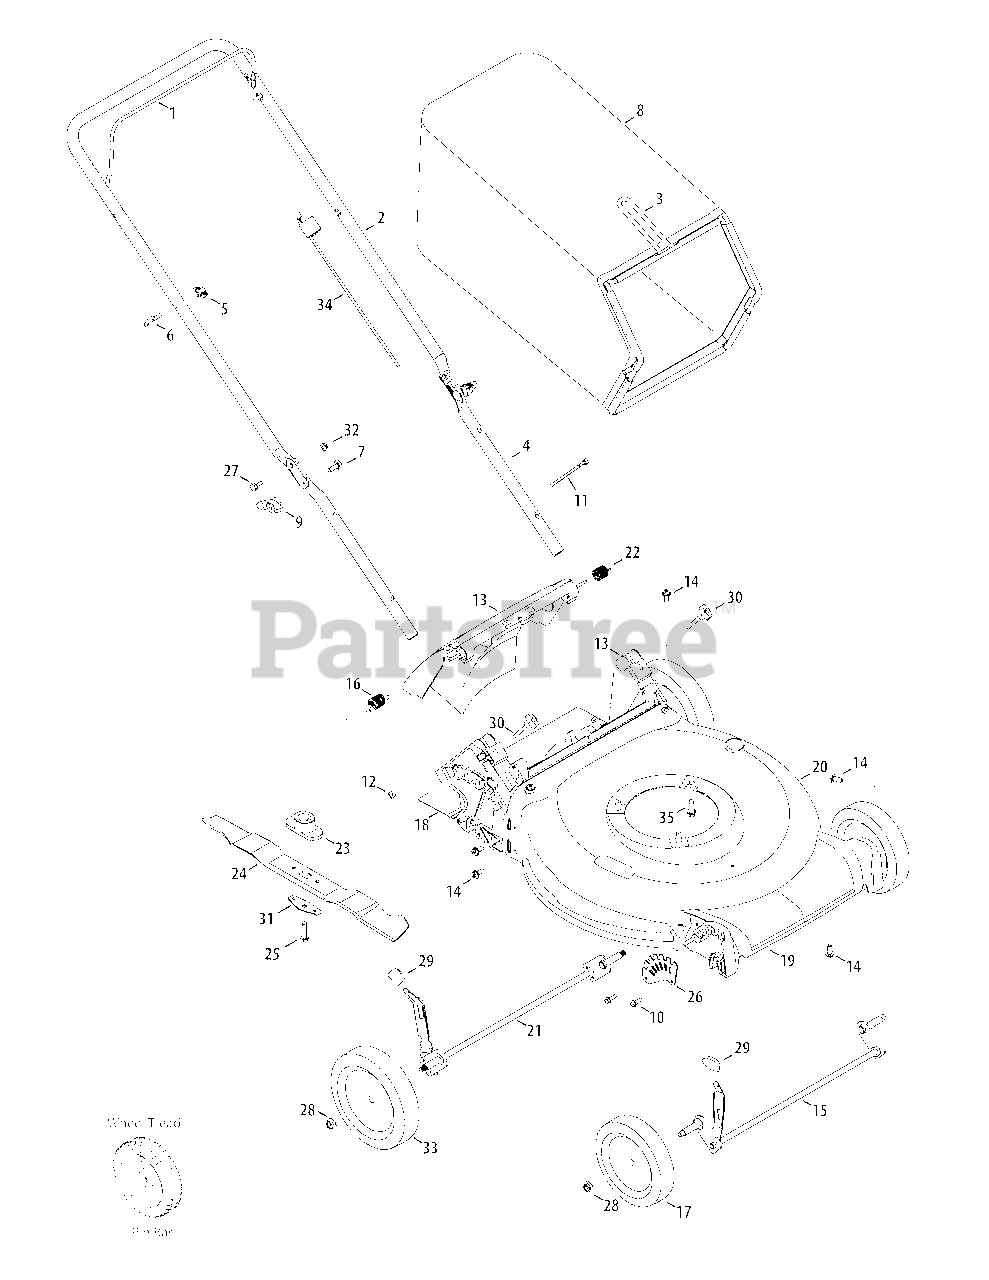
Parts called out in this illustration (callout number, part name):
1	Blade Control
2	Upper Handle
3	Grass Catcher Frame
4	Lower Handle
5	Wing Nut
6	Rope Guide
7	Carriage Screw ,5/16-18
8	Grass Bag
9	Wing Knob, Red
10	Screw, 1/4-15 x .750
11	Cable Tie
12	Nut, Sq., 1/4-20
13	Rear Door Assembly
14	Screw, 5/16-14 x .750
15	Front Axle Assembly
16	Torsion Spring - RH
17	Front Wheel, 7 x 1.8, Bar, Gray
18	Trail Shield
19	Front Cover
20	Deck - 21"
21	Rear Axle Assembly
22	Torsion Spring - LH
23	Blade Adapter
24	Mulching Blade
25	Screw , 3/8-24 x 1.50
26	Front Height Adjuster Plate
27	Sldr. Screw, .375 x .126 x 1/4-20
28	Flange Lock Nut, 3/8-16
29	Adjustment Lever Knob, Red
30	Wing Nut
31	Blade Bell Support
32	Nut, Flange Lock, 1/4-20
33	Rear Wheel, 8 x 1.8, Bar, Gray
34	Control Cable, 37.58"
35	TT Sems Screw, 3/8-16 x 1.0
